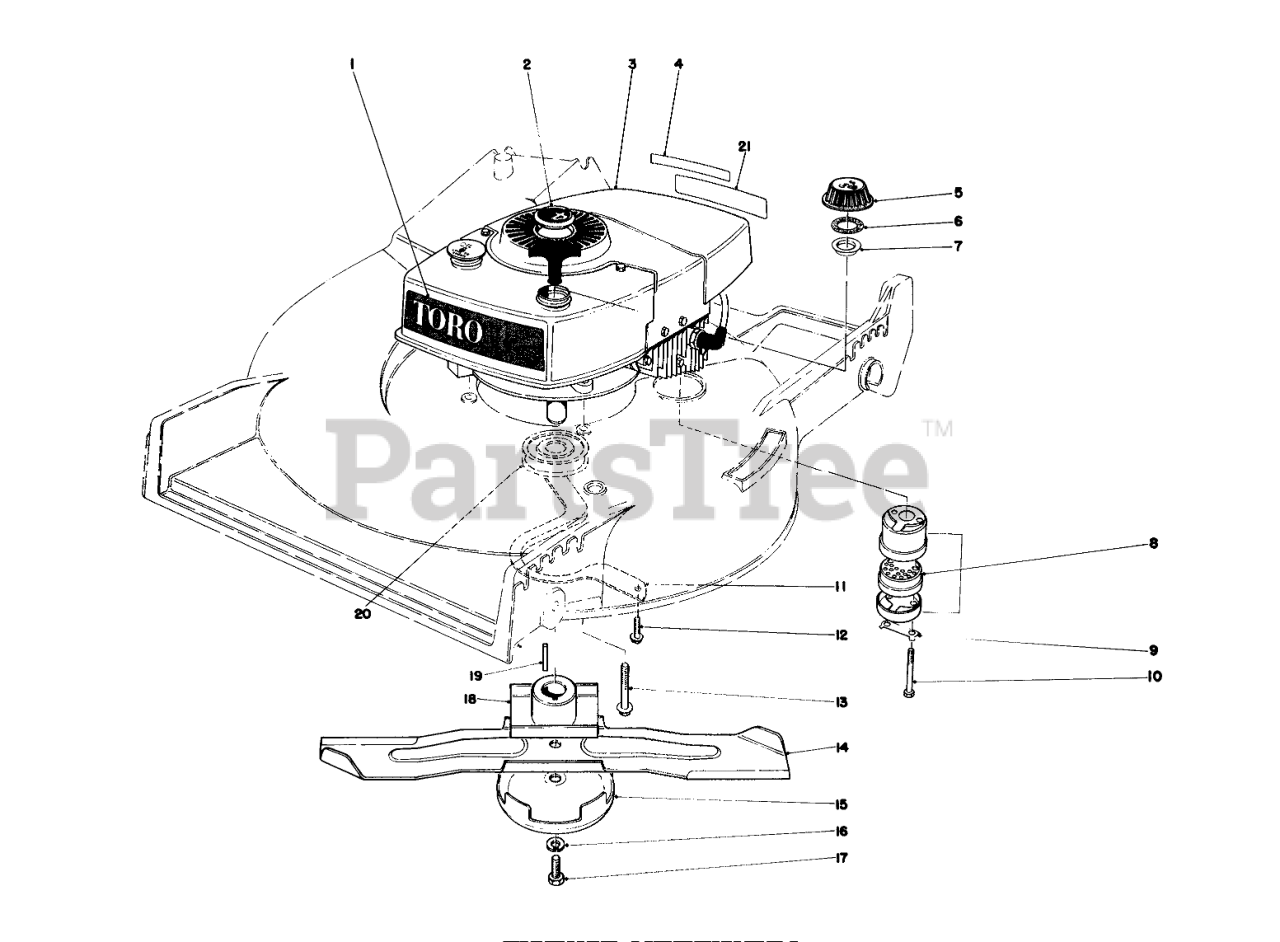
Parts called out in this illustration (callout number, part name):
1	Decal Toro
2	Plug Button
3	Engine
4	Decal-Primer Bulb
5	Gas Cap (Incl. Ref. #6 & 7)
6	GASKET
7	GAS CAP BAFFLE
8	Muffler Assembly (Incl. Ref. #9 & 10)
9	CLIP - LOCKING
10	SCREW-HH
11	BELT GUIDE
12	Screw
13	SCREW-HWHTF
14	Blade
15	AntiScalp Cup
16	WASHER-LOCK
17	BLADE SCREW
18	BLADE RETAINER WA(BLACK)
19	KEY-SQUARE
20	DRIVER PULLEY
21	Decal Maintenance
